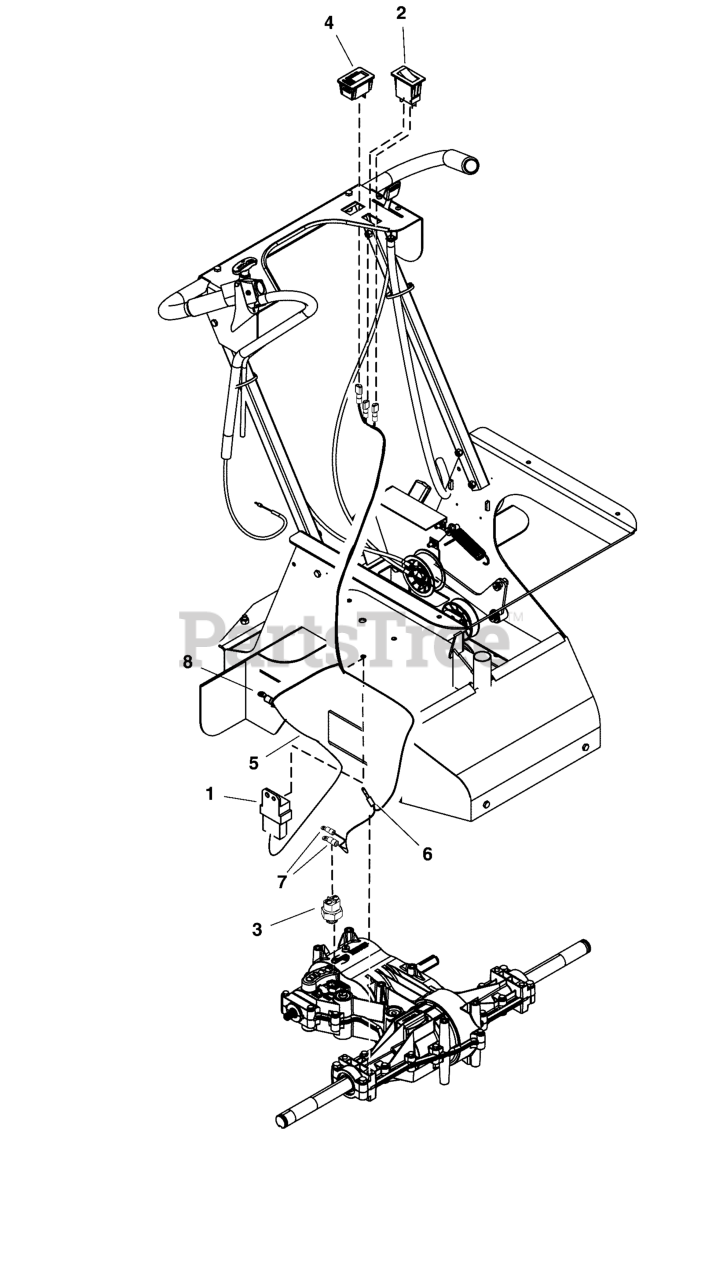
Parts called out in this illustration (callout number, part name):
1	MODULE, SAFE-START
2	SWITCH, ROCKER ON/OFF
3	PEERLESS NEUTRAL START SWITCH
4	METER, TACH/HOUR INDUCTIVE PICKUP
5	HARNESS, WIRING ROVER/ROVER XC
6	Connects to Engine
7	Connects to Neutral Start Switch
8	Connects to Ground
